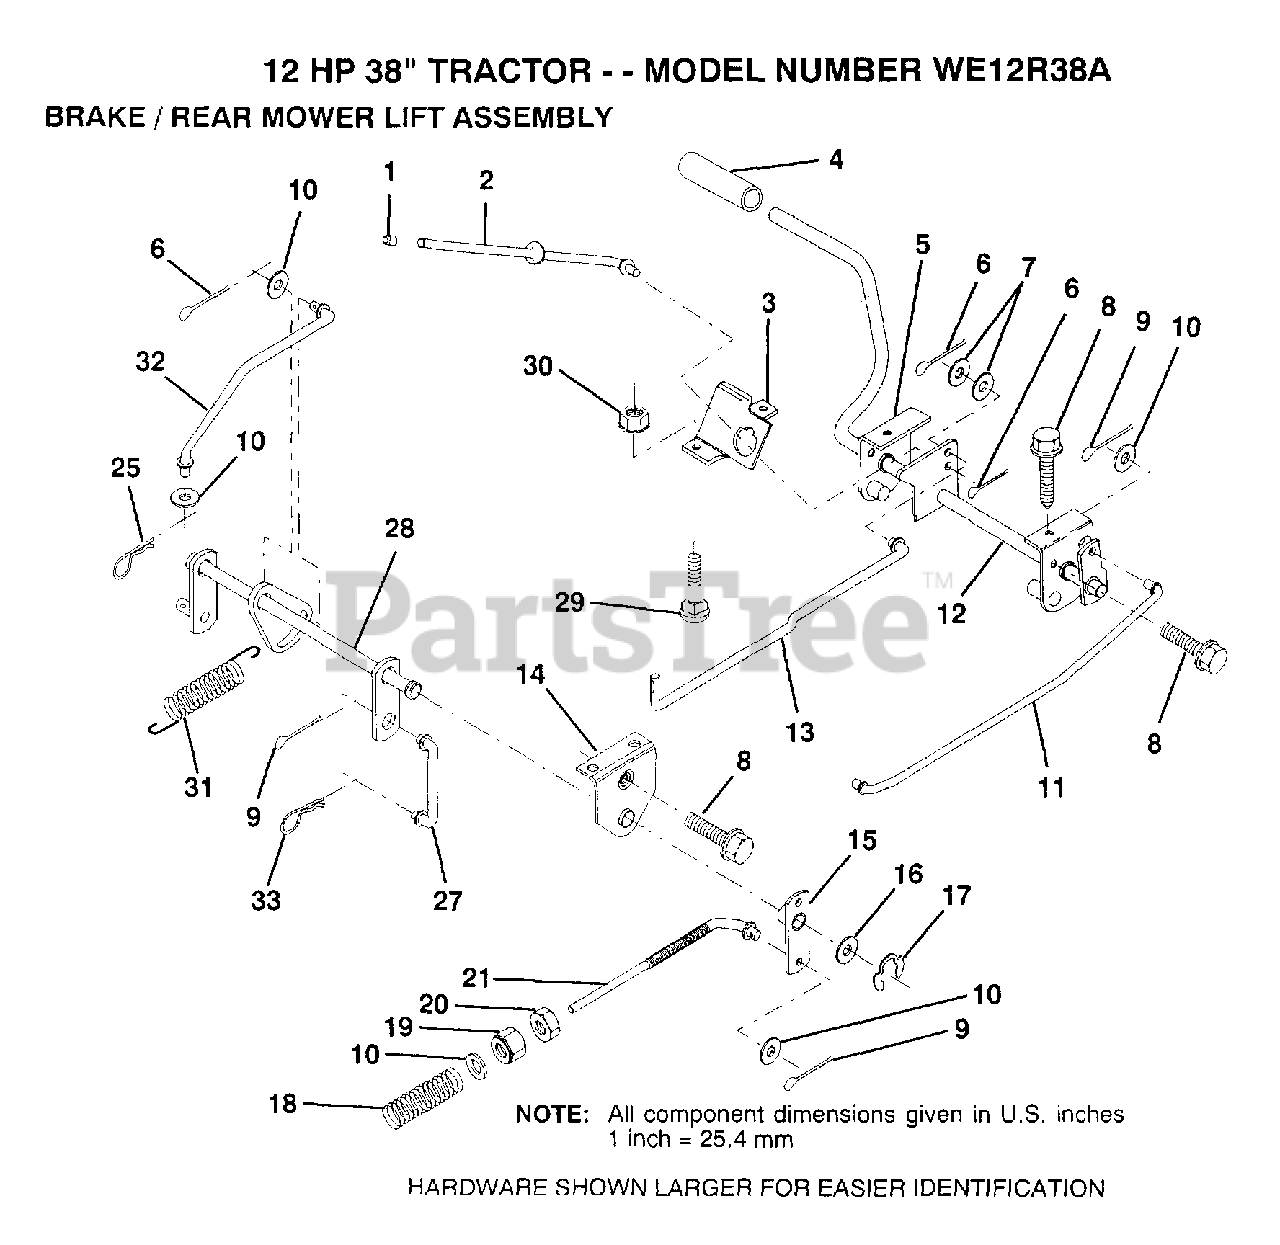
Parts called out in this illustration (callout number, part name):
1	PLUNGER CAP T
2	"ROD,PARK BRAKE"
3	"BRKT,PARK BRAKE"
4	PEDAL COVER T
5	BRK ASM CLUT LH
7	WASHER
8	SCREW LT
9	COTTER PIN
10	WASHER
11	"ROD,FRT BRAKE"
12	ASM CLUTCH/BRK PD
13	"ROD,CLUTCH"
14	"BRKT,LIFT SHAFT"
15	BRAKE PIVOT ARM
16	WASHER T
17	KLIP RING
18	SPRING ROD LT
19	NUT
20	NUT
21	ROD.BRAKE.REAR
25	SPRING.RETAINER
27	LINK LIFT REAR LR
28	LIFT ASM MWR RE
31	COUNTER SPRING
32	LINK LIFT LEVER
